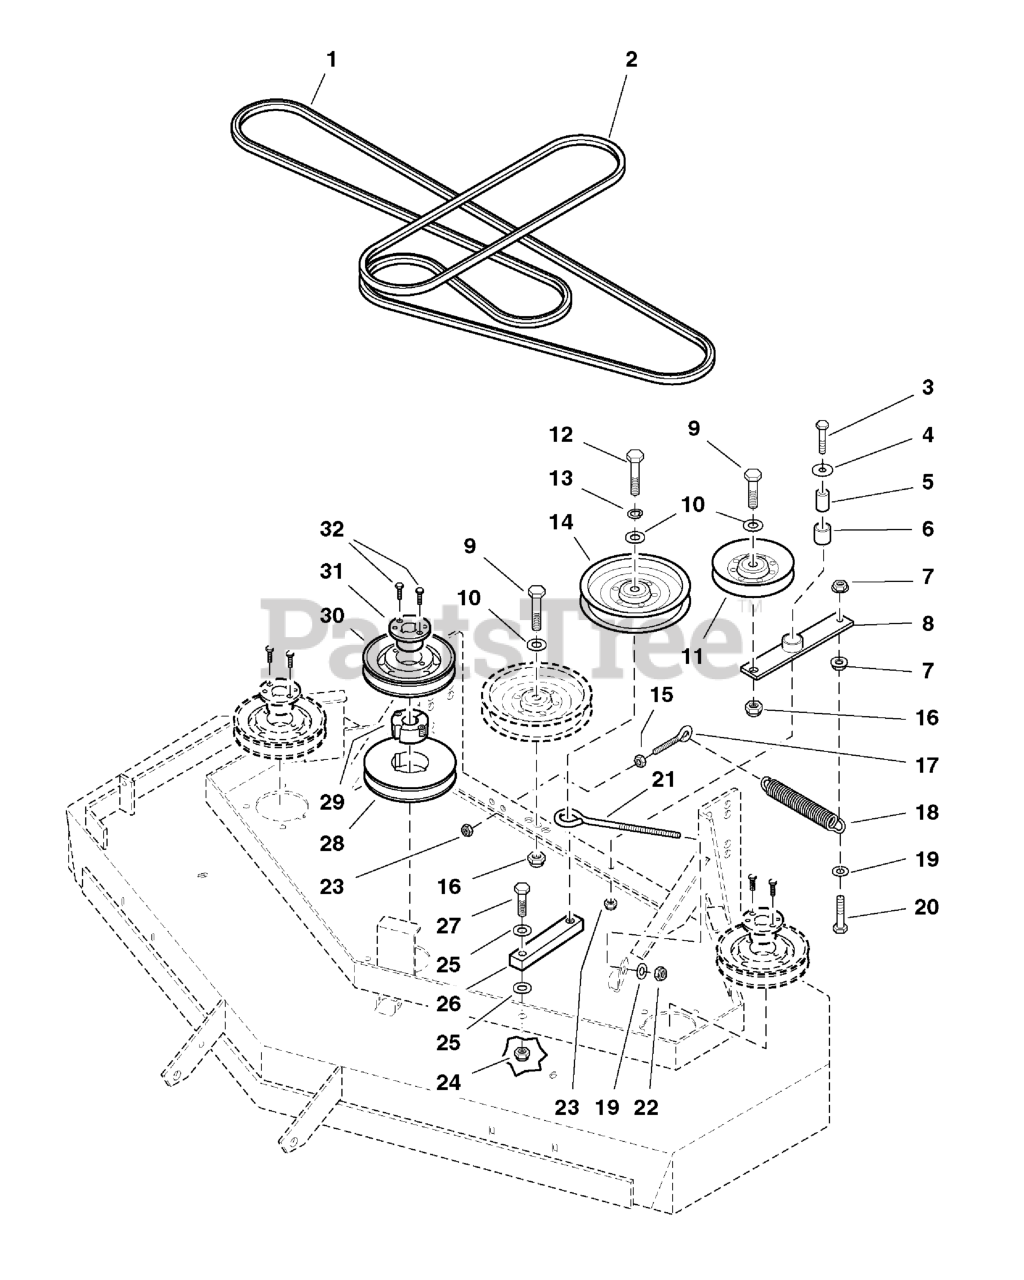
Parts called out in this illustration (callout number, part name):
1	BELT, Blade Spindle
2	BELT, Deck Drive
3	BOLT, 5/16-18 x 1-3/4
4	WASHER, 5/16" Fender
5	SPACER, .32 x .75 x 1.06
6	BUSHING, Brass
7	NUT, 3/8-16 Hex Serrated Flange
8	IDLER ARM, Complete
9	BOLT, 1/2-20 X 2-1/4 GD5 CZ
10	WASHER, 1/2 SAE
11	PULLEY, V-Idler
12	BOLT, 1/2-20 X 2-1/2" GD5 CZ
13	WASHER, 1/2" Lock
14	PULLEY, Backside Idler
15	NUT, 5/16-18 HEX
16	NUT, Hex, Nylon Lock, 1/2-20
17	EYEBOLT, 5/16-18 x 3-1/4
18	SPRING, Extension
19	WASHER, 3/8 SAE
20	BOLT, 3/8-16 X 2, GD5, CZ
21	EYEBOLT, 3/8" x 8"
22	NUT, 3/8-16 HEX NYLON LOCK
23	NUT, 5/16-18 Hex Nylon Lock
24	NUT, 7/16-20 Hex Nylon Lock
25	WASHER, 7/16" SAE
26	ARM, Idler
27	BOLT, 7/16-20 X 1-3/4" GD.5
28	PULLEY, Taper Lock
29	BUSHING, Taper Lock
30	PULLEY, Spindle
31	BUSHING, Tapered Hub
32	BOLT, 1/4-20 X 1" GD5 CZ
